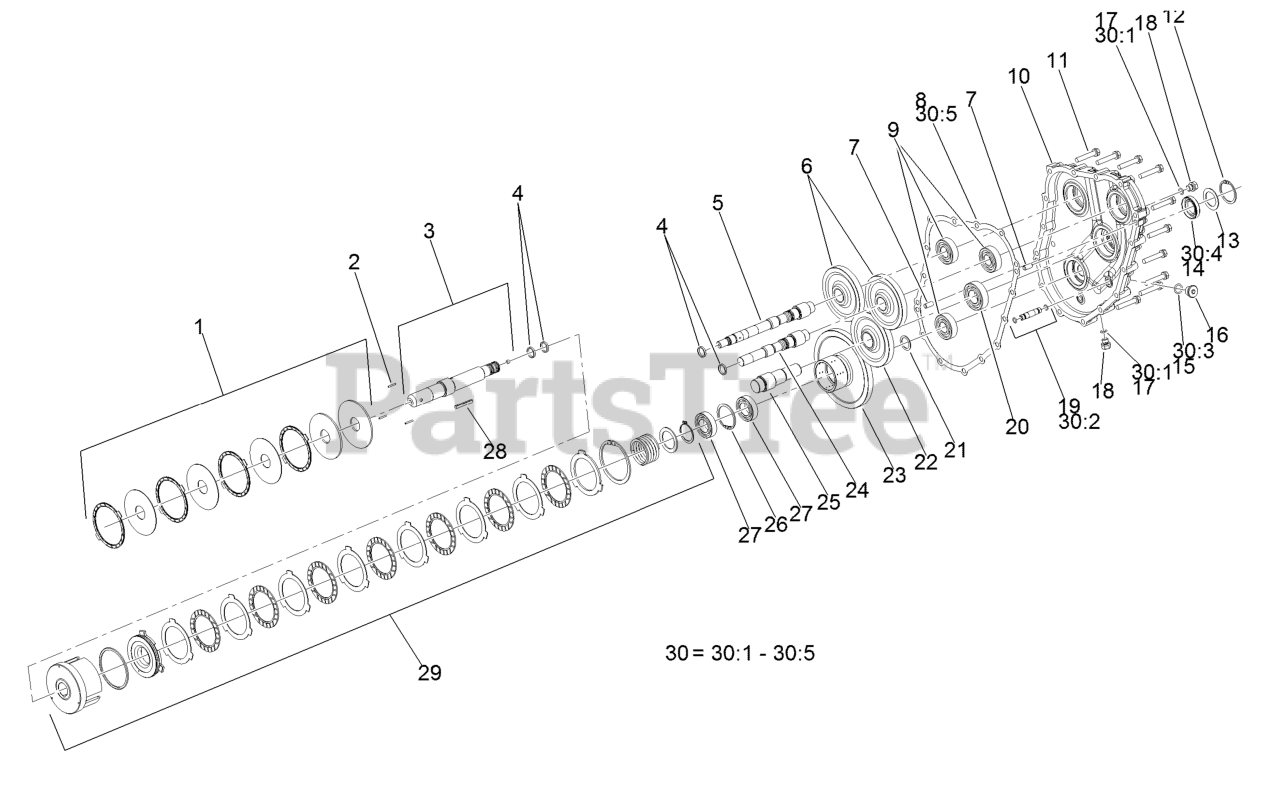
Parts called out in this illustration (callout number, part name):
1	PTO Brake ASM
2	Rod-Push
3	PTO Shaft ASM
4	Ring-Seal
5	Shaft-Pump
6	Gear-Pump
7	Pin-Parallel
8	Gasket-Housing, Gear
9	Bearing
10	Housing-Case, Gear
12	Ring-Snap
15	Packing
16	Plug-NPTF
17	O Ring-Plug
20	Bearing
22	Gear-Input
23	Gear-PTO
24	Shaft-Pump
25	Shaft-Input
26	Ring-Snap
27	Bearing
29	Clutch Cylinder ASM
30	Gear Housing Seal Kit
30:1	O Ring-Plug
30:2	O-Ring
30:3	Packing
30:5	Gasket-Housing, Gear
